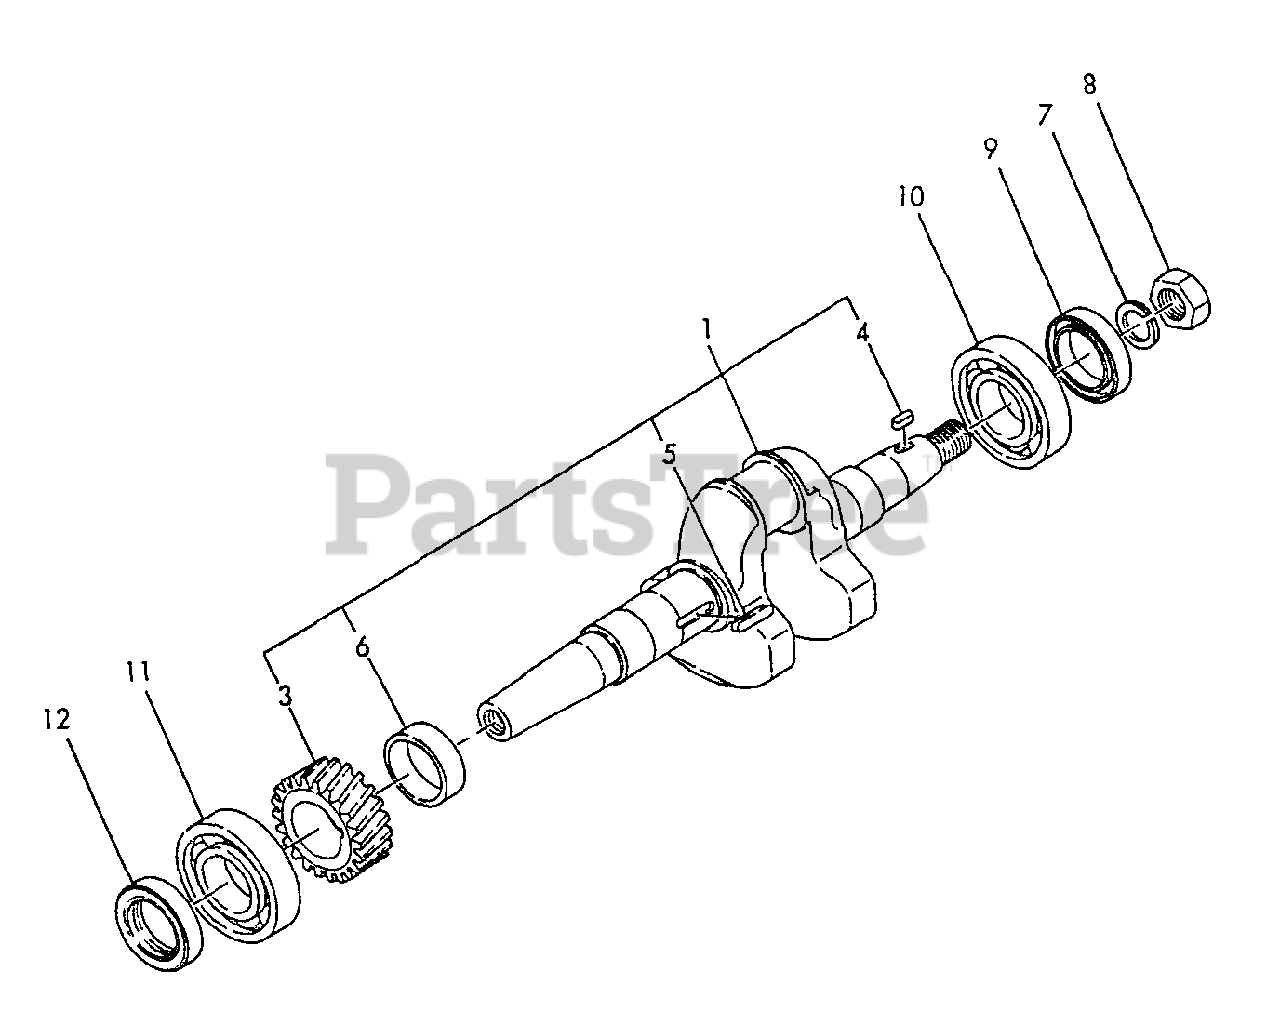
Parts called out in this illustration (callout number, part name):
1	CRANKSHAFT ASSY
3	GEAR, CRANKSHAFT
4	KEY - 4X10
5	KEY - 4X24
6	SPACER, GEAR
7	LOCKWASHER - 10
8	NUT - 16
9	SEAL, OIL
10	BEARING, BALL - 6205C3
11	BEARING, BALL - 6206C4
12	SEAL, OIL
